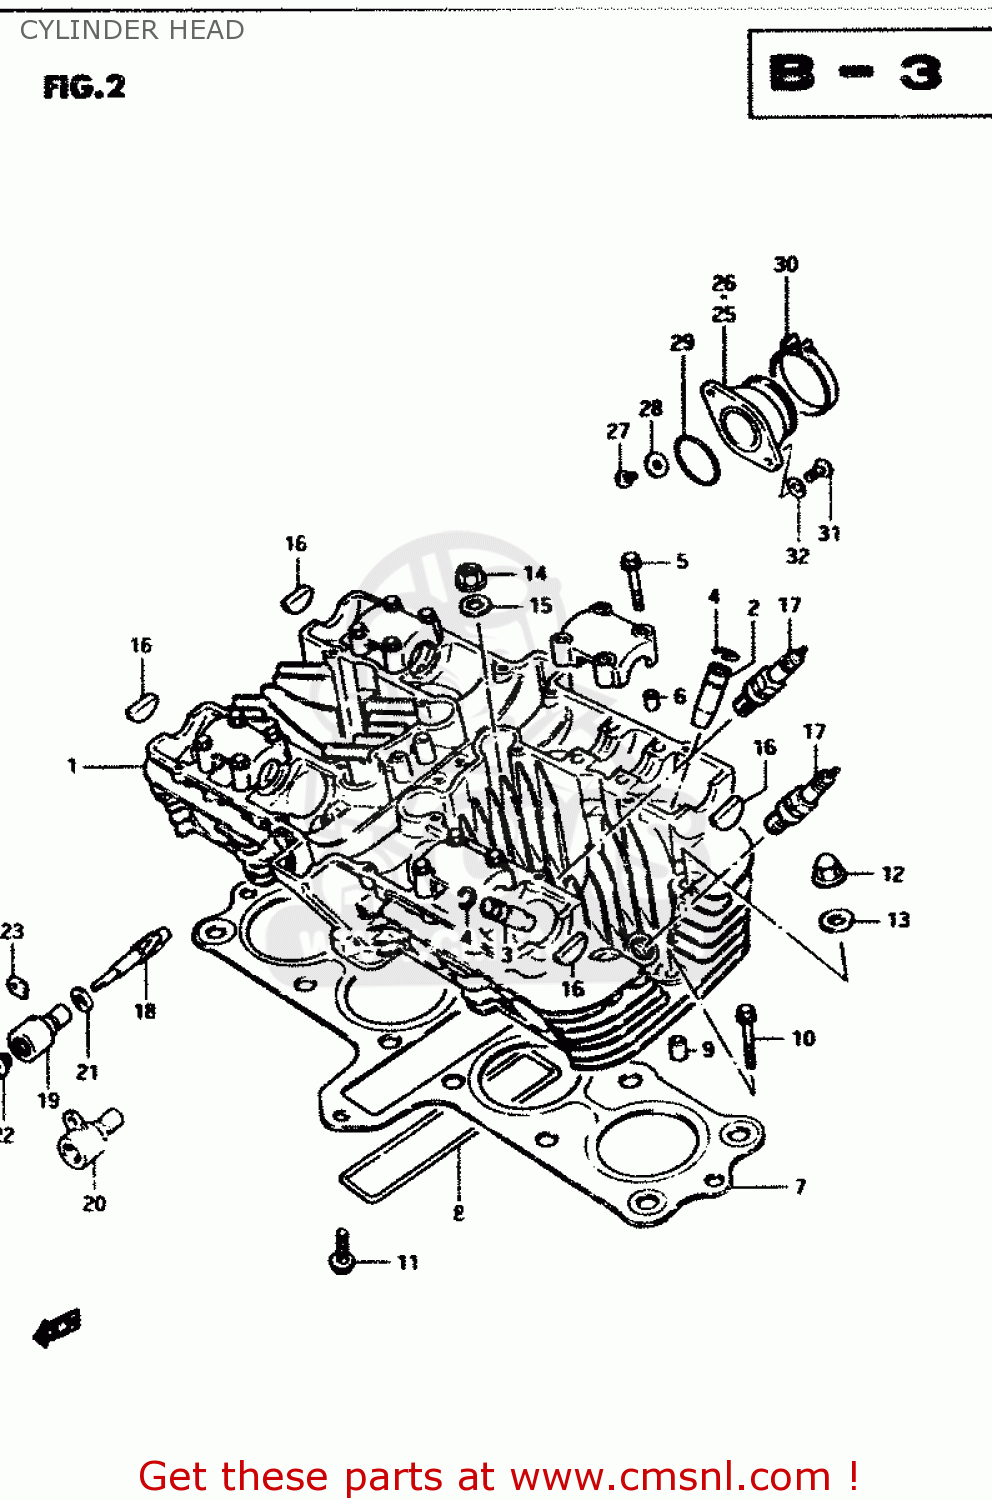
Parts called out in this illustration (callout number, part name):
1	HEAD ASSEMBLY,CYLINDER
2	GUIDE,INTAKE VALVE
3	GUIDE,EXHAUST VALVE
4	RING,SNAP
5	BOLT(6X39)
6	PIN(6.2X8X11)
7	GASKET,CYLINDER HEAD (MCA)
8	O RING(D:3,ID:26X157)
9	PIN
10	BOLT,UNDER
11	BOLT
12	NUT
13	GASKET(10.5X22X2) (NAS)
14	NUT
15	WASHER(10.5X22X2.3)
16	PLUG
17	PLUG,SPARK
18	GEAR,TACHOMETER DRIVEN
19	SLEEVE,TACHOMETER DRIVE
20	SLEEVE,TACHOMETER DRIVE GEAR
21	SEAL,TACHOMETER DRIVEN
22	SEAL,OIL(5X12X8)
23	PLATE,TACH DRIVE GEAR SLEEVE
24	SCREW(5X12)
25	PIPE,INTAKE,R
26	PIPE,INTAKE,L
27	BOLT
28	GASKET(5.3X9.3X1.2) (NAS)
29	O-RING
30	CLAMP
31	SCREW
32	WASHER
